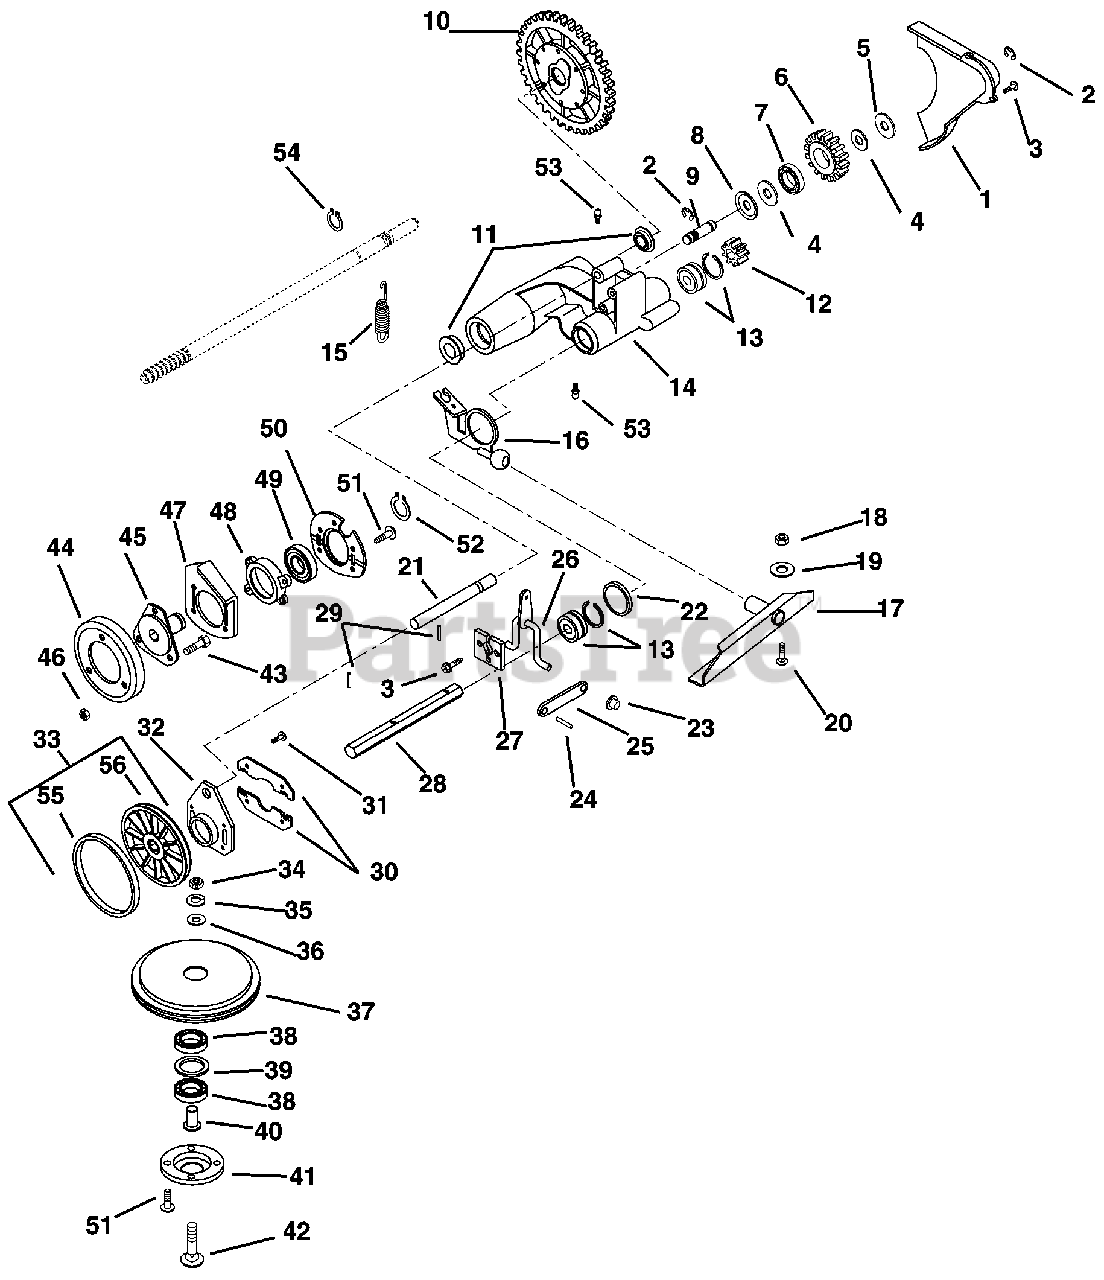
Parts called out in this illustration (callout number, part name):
1	Gear Cover
2	Ring-Retaining-External ,438 x .035
3	Screw-Tapping 12-24 x .50 Hex Washer Head
4	Washer - Flat - Steel .520 x.875 x .062
5	Washer - Flat - Steel .531 x 1.00 x .063
6	Idler Gear
7	Bearing - Ball .50 x 1.38 x .437
9	Idler Shaft
10	Differential Assembly
11	Bearing-Ball .625 x 1.383 x .50 (600 C)
12	Gear-Pinion
13	Bearing - Ball .562 x 1.375 x .437 (600 C)
14	Drive Mount
15	Spring-Tension .051 x .60 x 2.25
16	Drive Actuator Weldment
17	Pivot Channel Weldment
18	Nut-Locking-Center .31-18
19	Washer-Flat-Steel .344 x .688 x .065
20	Bolt-Round Head Square Short Neck .312-18 x .62
22	Washer - Flat - Steel 1.390 x 2.00 x .020
23	Push Nut .25
24	Pin-Roll .125 x .50 (580 RS, 580 RSE, 580 RSW)
25	Shift Link
26	Shift Arm Weldment
27	Retainer Plate
29	Pin - Roll .188 x .88
30	Thrust Plate
31	Screw-Tapping 10-24 x .375 (580 RS, 580 RSE, 580 RSW)
32	Guide-Plate (580 RS, 580 RSE, 580 RSW)
33	Friction Wheel Assembly
34	Nut-Hex .31-18
35	Washer-Locking .312 x .097 Heavy
36	Washer Flat-Steel .328 x .875 x .062
37	Friction Sheave
38	Bearing-Ball .625 x 1.375 x .43
39	Washer- Flat-Steel 1.062 x 1.344 x .032
40	Spindle Bearing
41	Bearing Retainer
42	Bolt-Round Head Square Neck .31-18 x 1.75 Grade 5 (600 C)
43	Bolt-Hex .25-20 x .50 Grade 5 (600 C)
44	Friction Disc (600 C)
45	Friction Wheel Hub (600 C)
46	Nut-Locking-Center .25-20 (600 C)
47	Bearing Plate (600 C)
48	Bearing Retainer (600 C)
49	Bearing Ball 1.00 x 2.00 x .56 (600 C)
50	Bearing Retainer (600 C)
51	Screw-Tapping 12-24 x .50 Hex Washer Head
52	Ring-Retaining - External 1.00 x .042 (600 C)
53	Fitting-Lube .25-28 x .256 (580 RSW, 600 C)
54	Ring-Retaining-External .579 x .930
55	Friction Ring (580 RS, 580 RSE, 580 RSW)
56	Friction Wheel Hub (580 RS, 580 RSE, 580 RSW)
